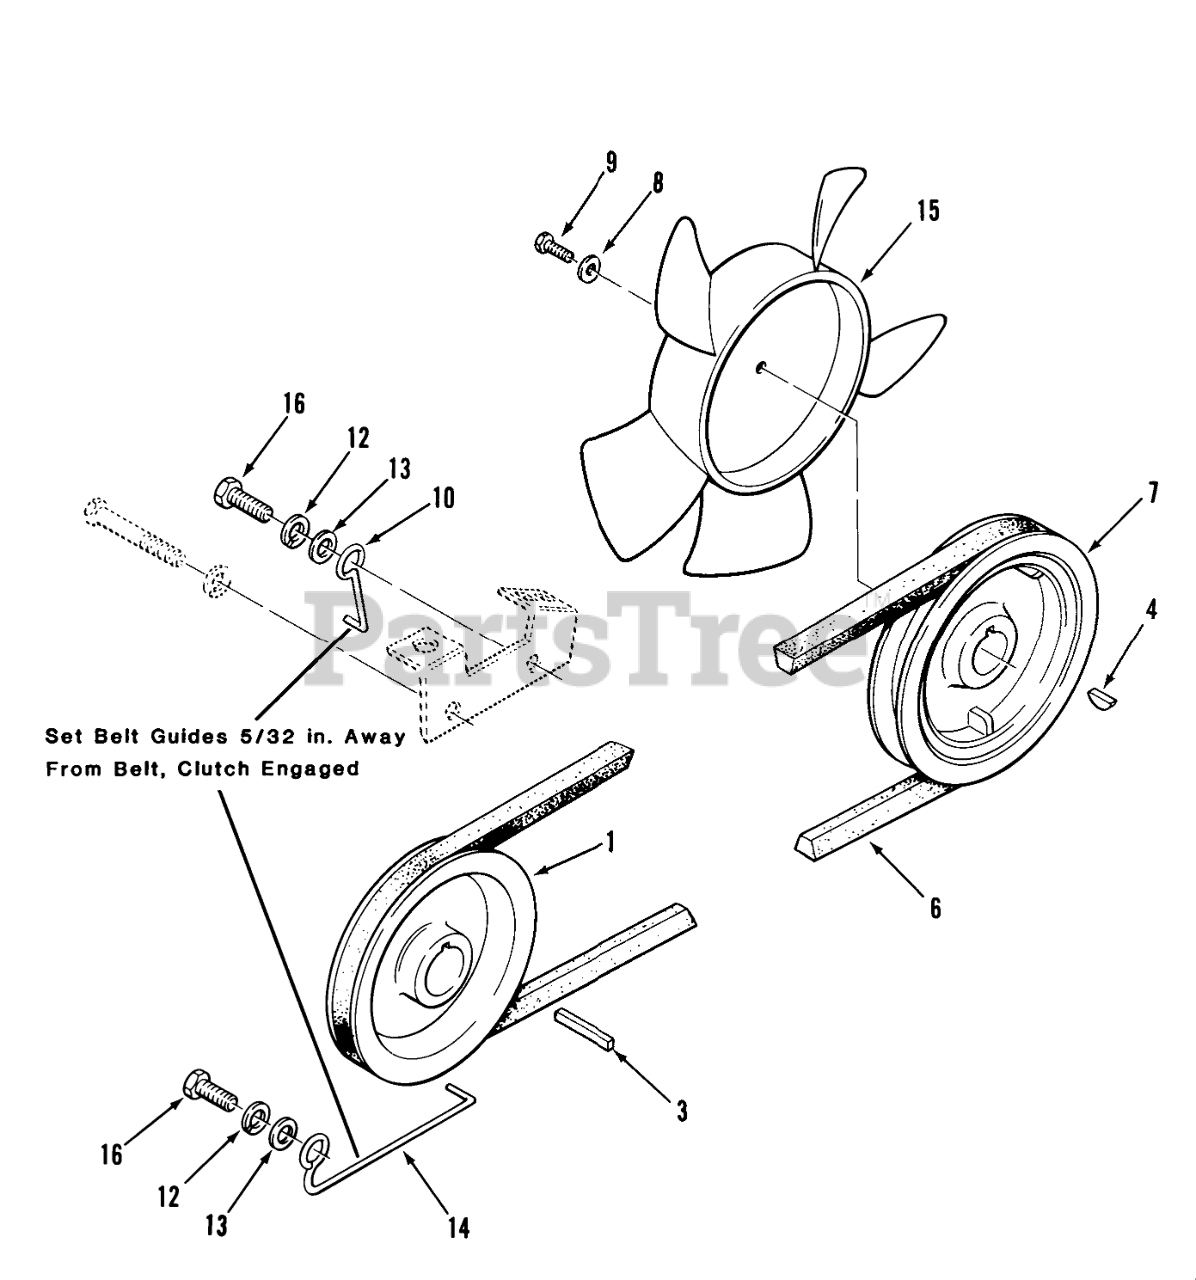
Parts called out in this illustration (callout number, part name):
1	ASSY ENGINE PULLEY
3	KEY-SQUARE
4	KEY-WOODRUFF
6	V-BELT
7	PULLEY
8	WASHER
9	H H C S
10	Belt Guide-Top
12	LOCKWASHER
13	WASHER
14	Belt Guide-Bottom
15	NYLON FAN-L-CW
16	7/16-14 x 1 1/4 Bolt
